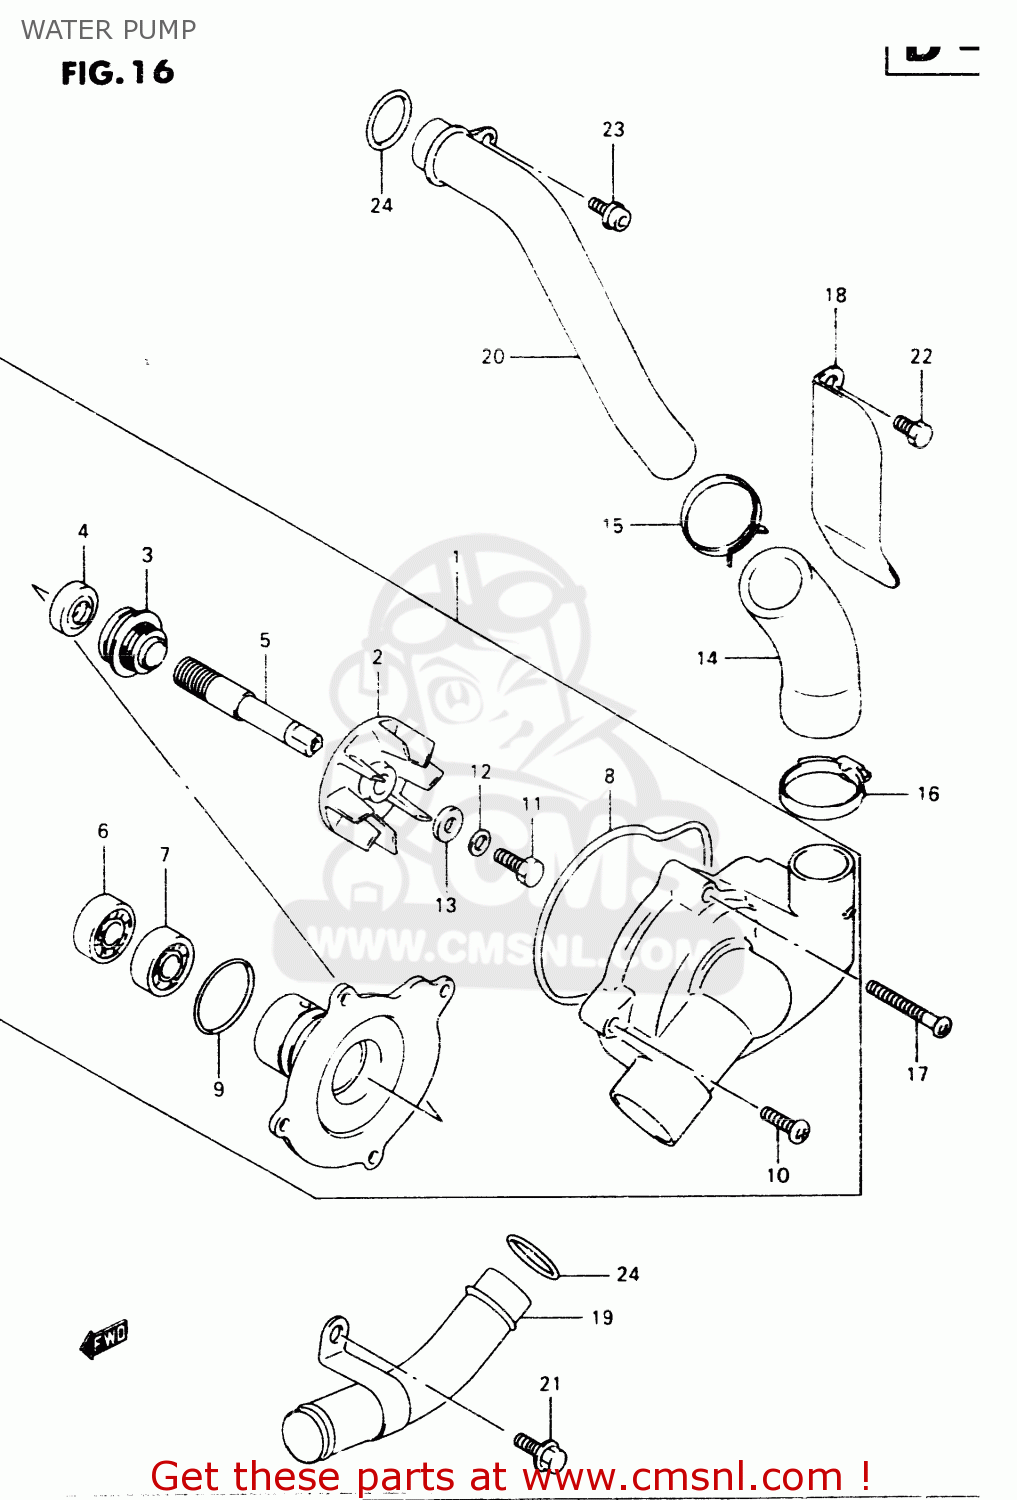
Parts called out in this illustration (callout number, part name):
1	PUMP ASSY,WATER
2	IMPELLER
3	SEAL,MECHANICAL
4	SEAL,OIL(10X21X5)
5	SHAFT
6	BEARING(10X26X8)
7	BEARING(12X28X8)
8	O RING
9	O RING,WATER PUMP HOLDER
10	SCREW 6X16
11	BOLT(6X13)
12	WASHER
13	GASKET(6X15X2.2) (NAS)
14	HOSE,WATER PUMP OUTLET
15	CLAMP
16	CLAMP
17	BOLT
18	PLATE,WATER HOSE
19	PIPE,WATER PUMP INLET
20	PIPE,WATER PUMP OUTLET
21	BOLT
22	BOLT
23	BOLT
24	O RING(D:2.7,ID:21.4)
